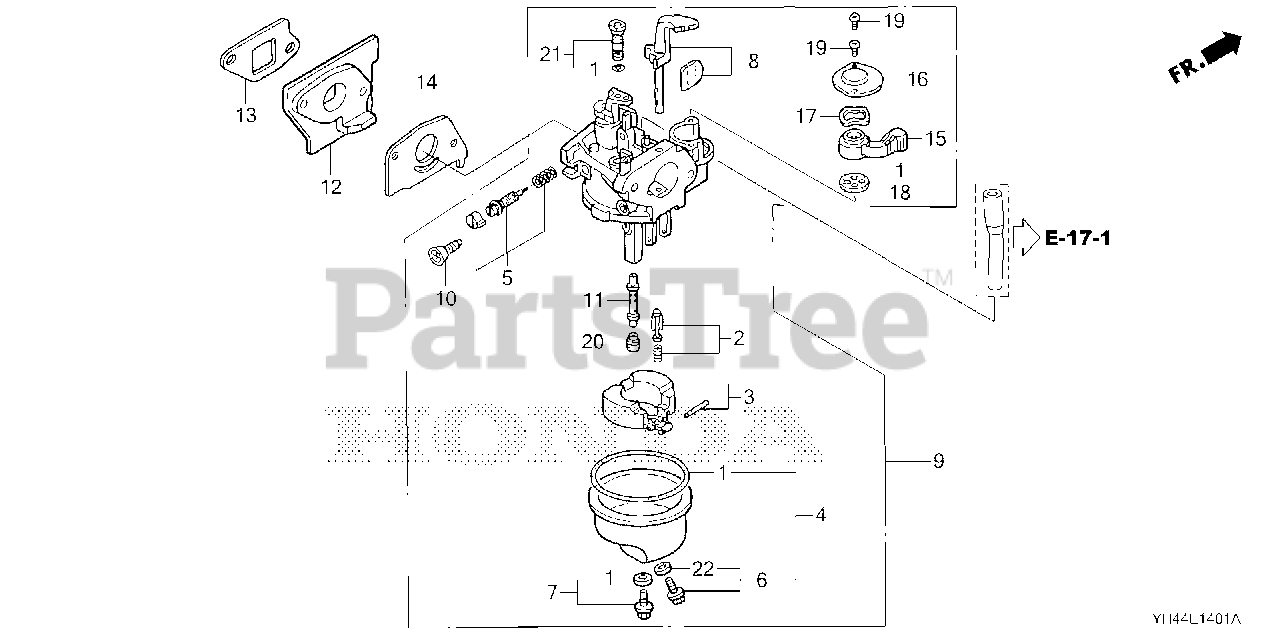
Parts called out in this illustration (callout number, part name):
1	GASKET SET
2	VALVE SET, FLOAT (CARBURETOR NO.) (SEAT NOT INCLUDED)
4	CHAMBER SET, FLOAT (CARBURETOR NO.)
5	SCREW SET (Honda Code 4219879). (CARBURETOR NO.)
5	SCREW SET
6	SCREW SET, DRAIN (Honda Code 1672187). (CARBURETOR NO.)
7	SCREW SET (CARBURETOR NO.)
8	CHOKE SET (CARBURETOR NO.)
9	CARBURETOR ASSY. (BF32M A)
10	SCREW, THROTTLE STOP
11	NOZZLE, MAIN (CARBURETOR NO.)
12	INSULATOR, CARBURETOR
13	GASKET, INSULATOR (ENGINE NO.)
14	GASKET, CARBURETOR
15	LEVER, VALVE (CARBURETOR NO.)
16	PLATE, LEVER SETTING (CARBURETOR NO.)
17	SPRING, PETCOCK LEVER (CARBURETOR NO.)
18	GASKET, VALVE
19	SCREW, PAN (3X6)
20	JET, MAIN (#48) (CARBURETOR NO.)
20	JET, MAIN (#50) Use from Engine SN BF12A B.
20	JET, MAIN (#52) Use from Engine SN BF12A B.
21	JET SET, PILOT (#35)
22	WASHER, PLAIN (6.2X10.7 DRAIN) (CARBURETOR NO.)
